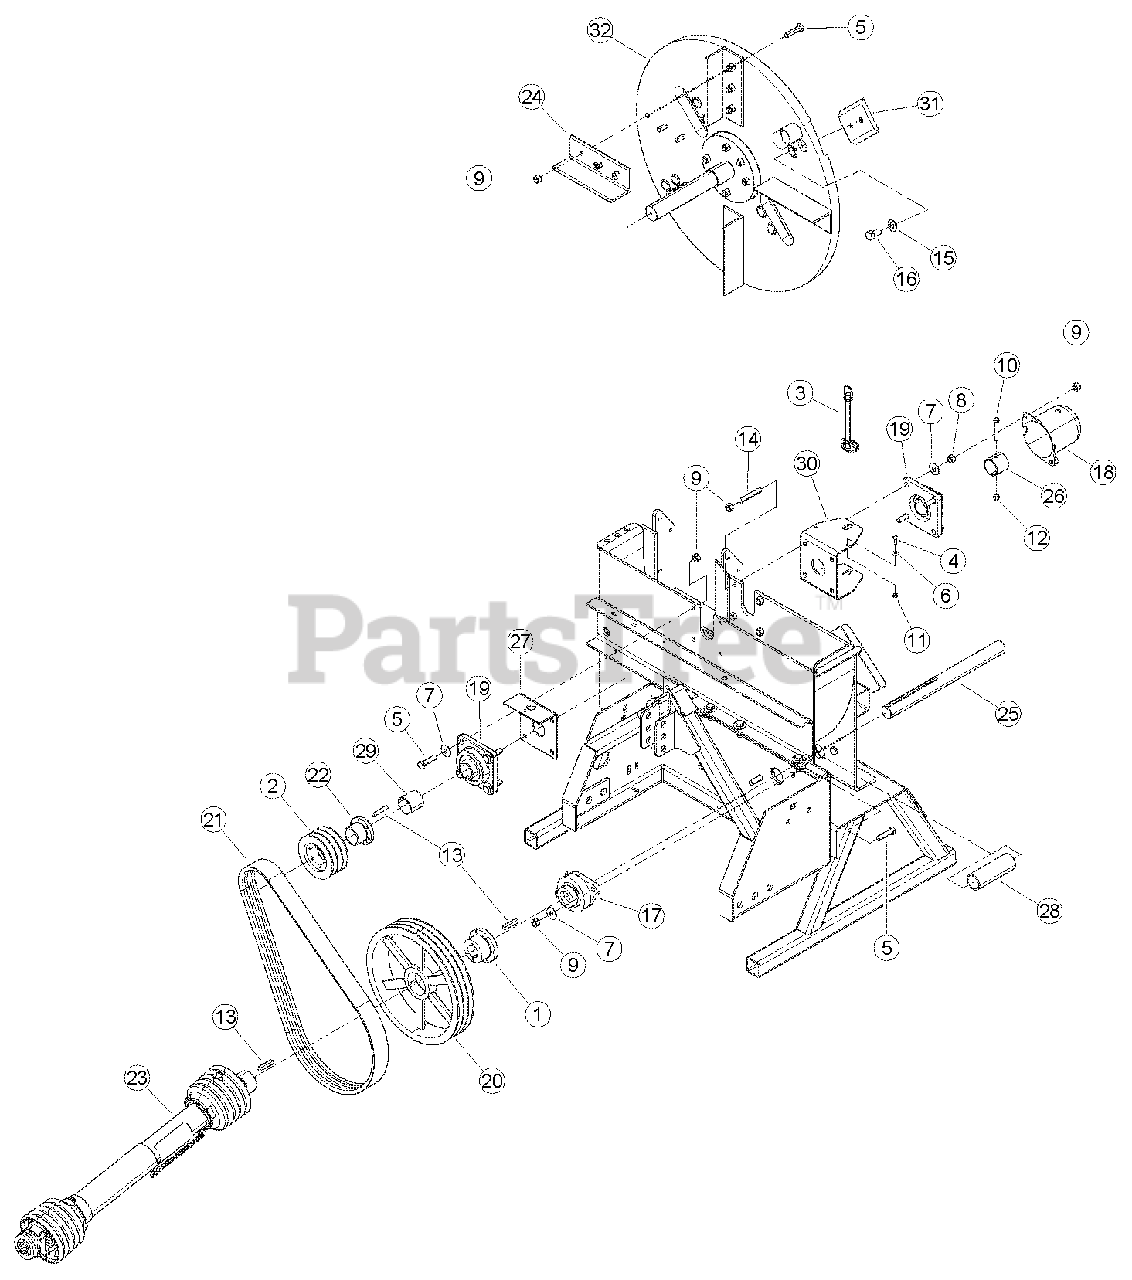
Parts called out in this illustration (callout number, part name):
1	BUSHING, SK 1-1/2"
2	SHEAVE 3B4.8 SD
3	PIN, HITCH 1/2 X 6-1/2 W LYNCH
4	BOLT, 1/4 X 3/4 HEX HD GR5 ZP
5	BOLT, 1/2 X 2 HEX HD GR5 ZP
6	WASHER, 1/4 FLAT ZP
7	WASHER, 1/2 FLAT ZP
8	NUT, 1/2 HEX NC ZP
9	NUT, 1/2 CENTERLOCK GRB ZP
10	BOLT, 3/8 X 2-1/2 HEX HD GR5 ZP
11	NUT, 1/4 NE NYLOCK ZP
12	NUT, 3/8 NE NYLOCK ZP
13	KEY, 3/8 SQUARE X 2 LONG PLAIN
14	STUD, 1/2-13 X 3 LONG B7 ZP
15	WASHER, 5/8 SAE HARDENED
16	BOLT, M16 X 2.0 X 30 HEX HD W/PATCH
17	BEARING, 2 BOLT FLANGE 1-1/2" BORE
18	CAP, LARGE SHAFT
19	BEARING, 4 BOLT FLANGE 1-3/4" BORE
20	SHEAVE, 3B13.6 SK
22	BUSHING, SD 1-3/4"
23	DRIVESHAFT. (WAS PN 16958, REPLACED AND SUPERSEDED. FOR SERVICE ORDER PN 32219-00 DRIVELINE)
24	PADDLE, BIG CHIPPER
25	JACKSHAFT, CHIPPER DRIVE
26	COLLAR, CHIPPER LOCK
27	WELDMENT, LEFT BEARING BRACKET
28	SHIELD, SHAFT
29	SPACER, 2.0 X 1.88
30	BRACKET, DISK LOCK
31	BLADE, BIG CHIPPER
32	ASSEMBLY, 9 INCH CHIPPER DISK
